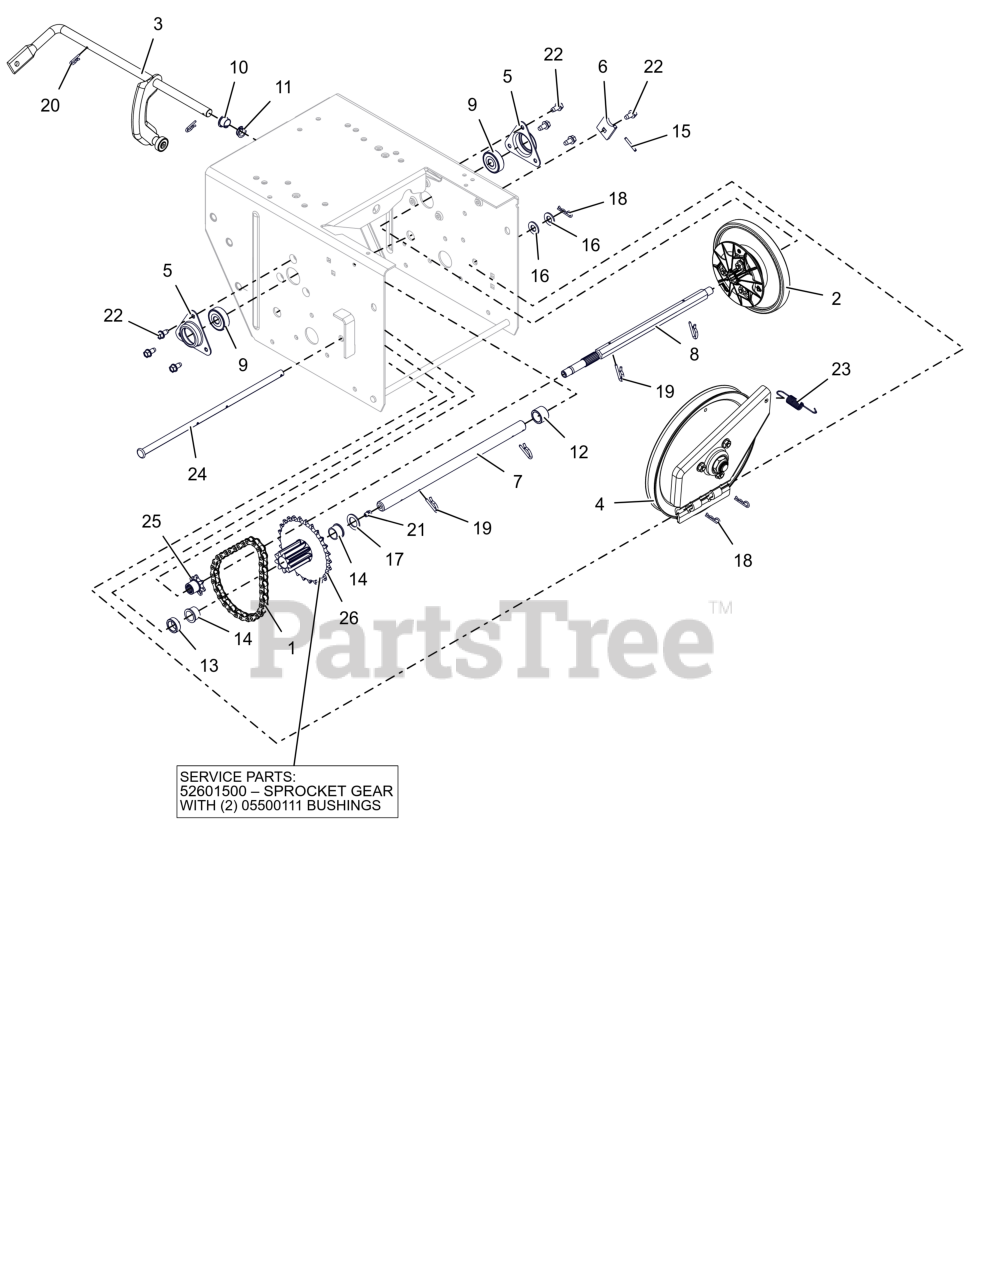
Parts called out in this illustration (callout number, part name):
1	CHAIN - #41, 32 PITCHES
2	DISC, FRICTION DRIVE-ASSEMBLY
3	ARM, SHIFT-PRO (ASSEMBLY)
4	PLATE, SWING ASSEMBLY-DEEP
5	FLANGE, BEARING
6	TAB, ANTI ROTATION
7	SHAFT, PINION - HARDENED
8	SHAFT, HEX - HEAT TREATED
9	BRG-BALL .437X1.375X.437
10	BUSHING, POLYLINER-.50 SPLIT
11	BUSHING, POLYLINER-.50 SNAPIN
12	SPACER, .635X.880X.611
13	BSHG-SLV, .635X.880X.305
14	BSHG-FLG .625X.750X.500X.875
15	PIN-ROLL .125X1.00
16	WSHR,FLT .406X.812X.065 ZCC
17	WSHR, FLT .630X1.005X.062 ZCC
18	PIN, HAIR #213 .08X1.19 ZCC
19	PIN, SPRING CLIP
20	CLIP, SPRING
21	ZERK,FITTING .25X.125 DRIVE IN
22	SCR-TAP .25-20X.50 HWH ZCC
23	SG-TENS .048X.50X2.8
24	PIN, PIVOT
25	SPROCKET- PINION 7T W/SPLINE
26	PINION & SPROCKET
26	PINION & SPROCKET W/BUSHINGS
